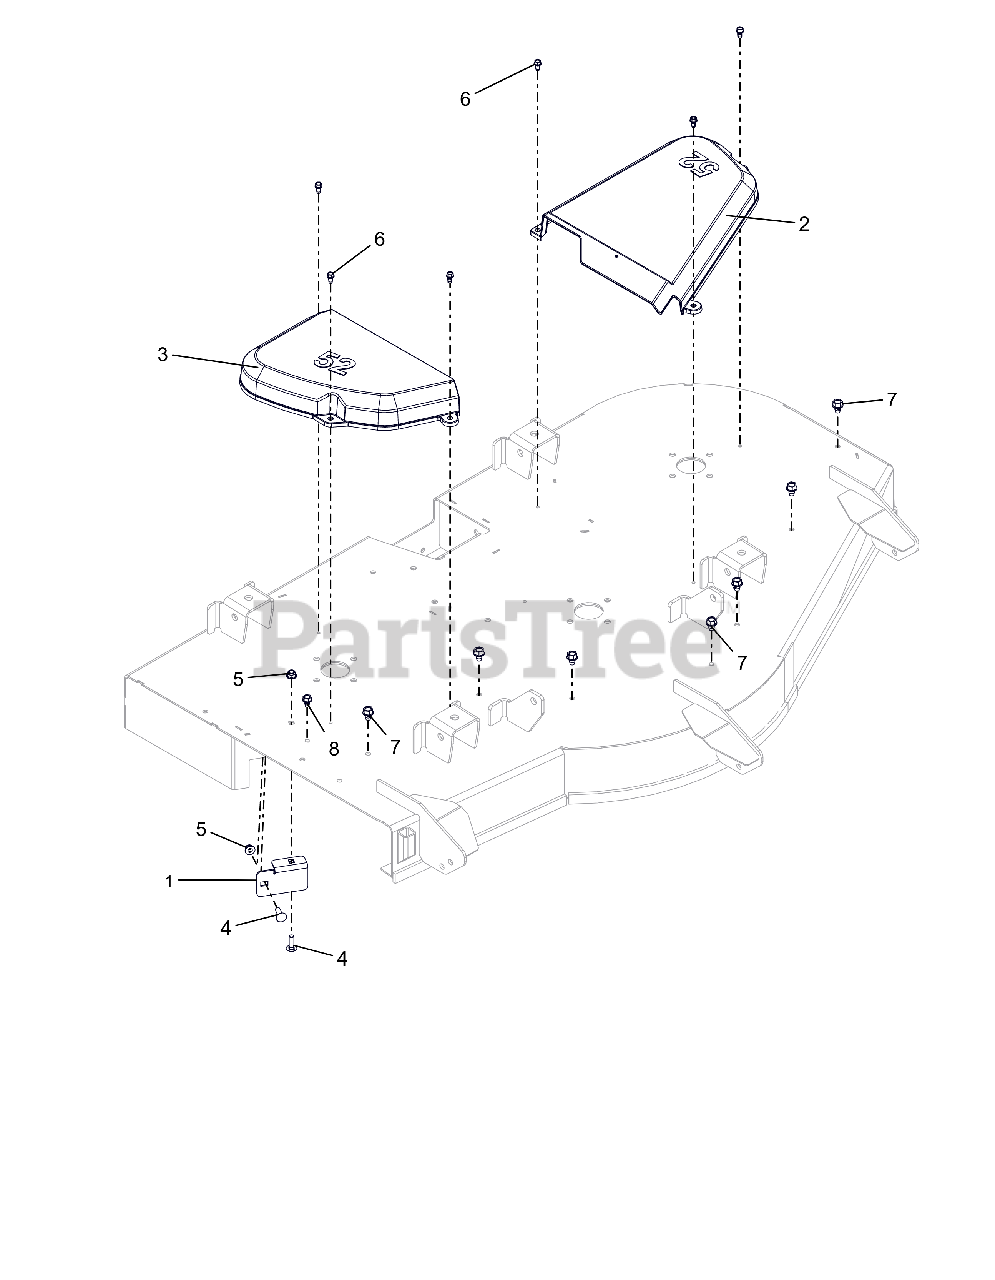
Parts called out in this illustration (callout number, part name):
1	STRIP, DEFLECTOR - 52"
2	COVER, BELT 52" LH
3	COVER, BELT 52" RIGHT
4	BLT,RHSN .31-18X1.00 G5 ZCC
5	NUT,LK-NYL-FLG .31-18 G5ZC120
6	SCR-TAP .25-20X.50 HWH ZCC
7	SCR,TAP .375-16X.50 HWH TR ZCC
8	@SCR-TAP .31-18X.50 HWH TR YWZ
